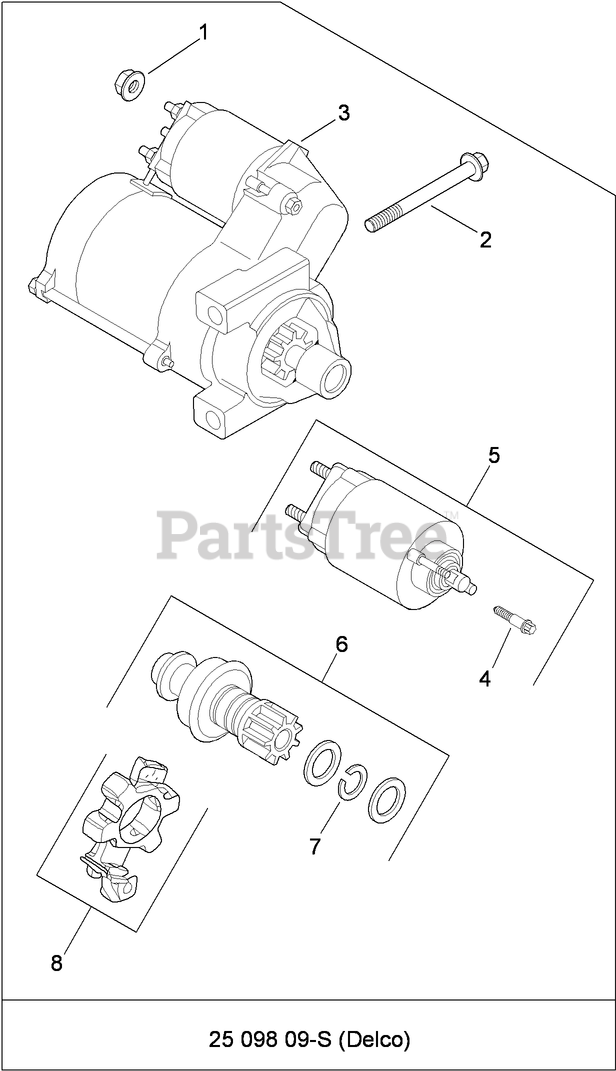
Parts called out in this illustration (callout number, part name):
1	NUT-FLANGE (M8X1.25)
2	SCREW-FLG (M8X1.25X80)
3	Starter ASM (SOLENOID SHIFT) (Includes Ref 4-8)
4	Screw-External Torx Head
5	Solenoid Kit (Includes Ref 4)
6	Pinion Drive Kit (Includes Ref 7)
7	RING-RETAINING
8	BRUSH HOLDER KIT
